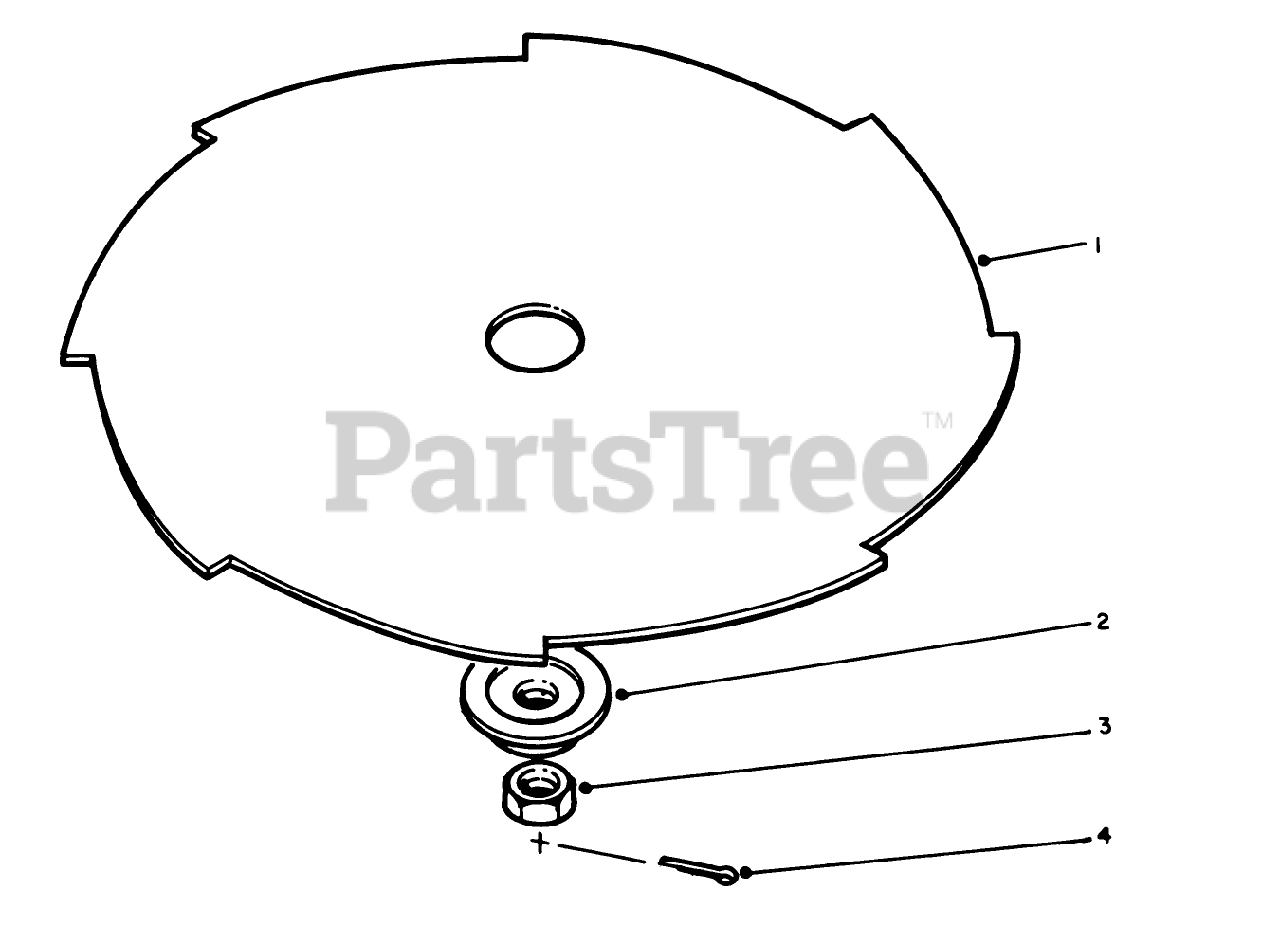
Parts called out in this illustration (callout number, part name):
1	BRUSH BLD PKG(8",8T)
2	Adapter-Blade
4	1/16 X 1 LG COTTER PIN
